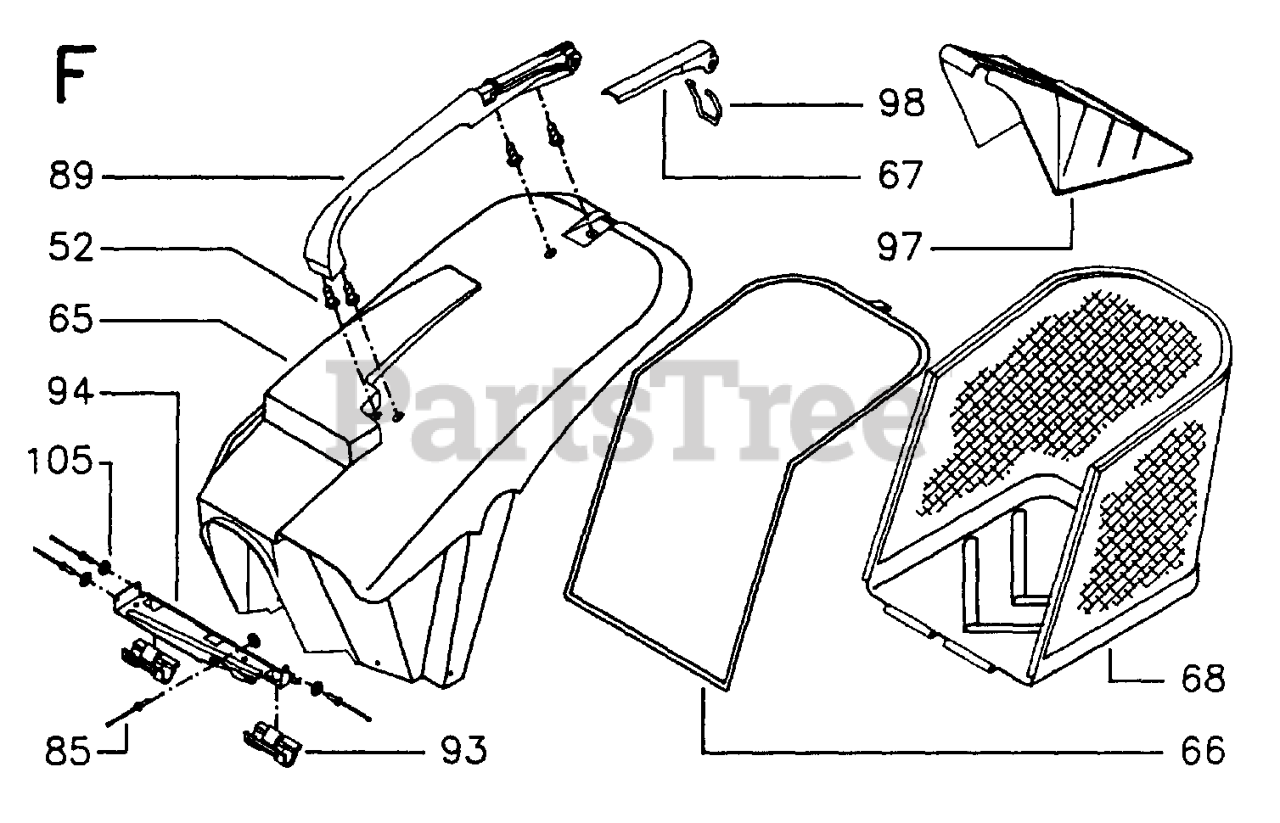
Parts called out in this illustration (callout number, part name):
52	SCREW
85	REPL BY 516 92 38-00
97	REPL BY 997 00 85-15
